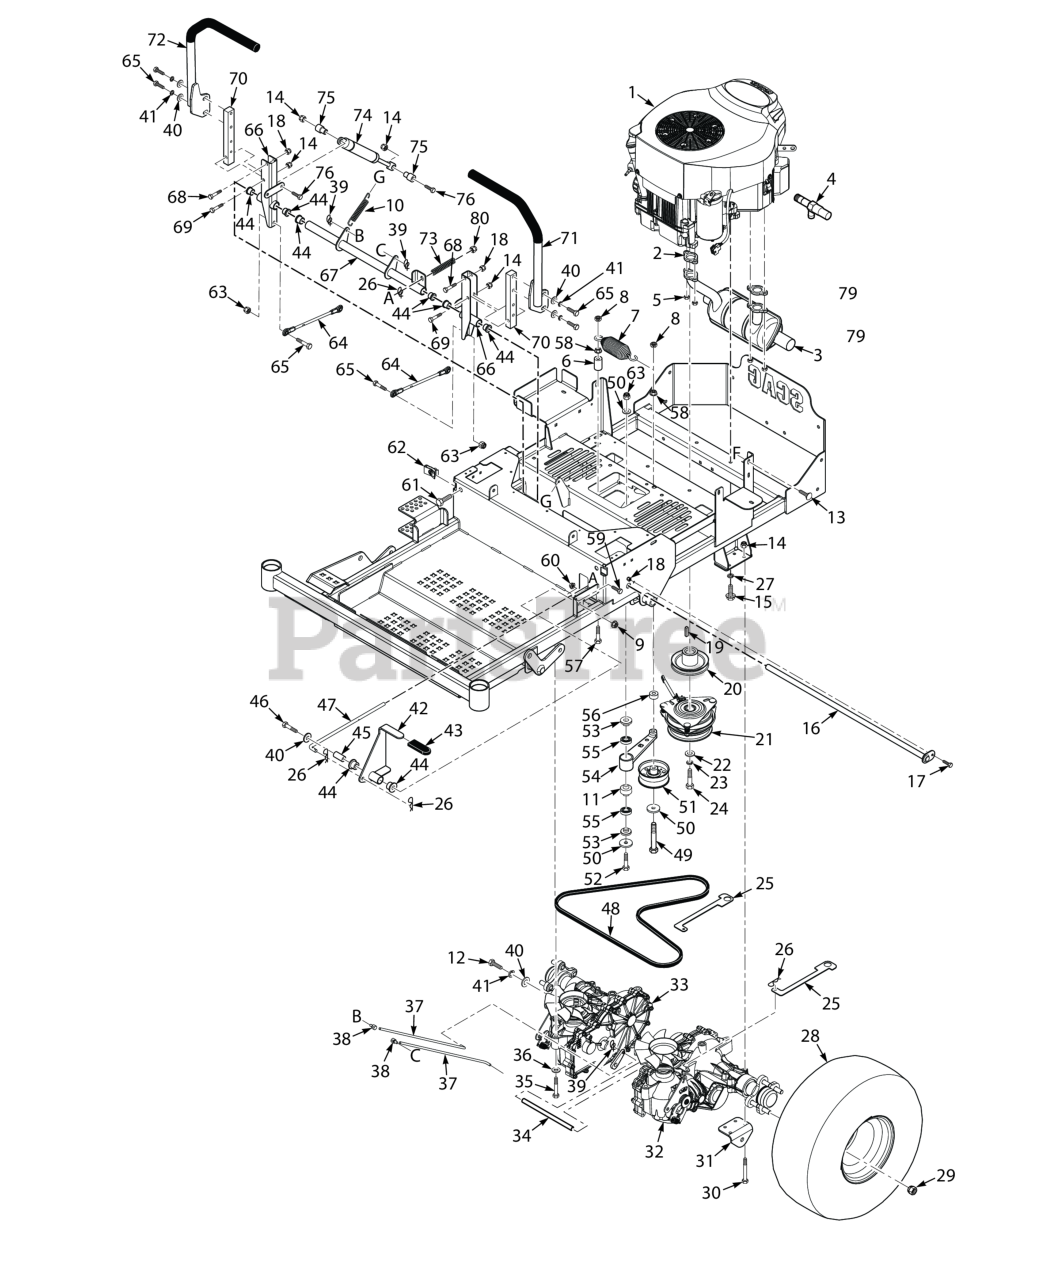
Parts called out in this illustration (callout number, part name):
1	Engine, Kawasaki 21FR
2	Gasket, Exhaust
3	Muffler, Kawasaki FR651V & FR691V
3	Muffler, Kohler KT
4	Oil Drain, Kawasaki
5	Nut, M8 x 1.25 Hex Special
6	Spacer, Idler Pulley - SFZ52
7	Spring, Transmission Drive
8	Bolt, Hex Head 3/8-16 x 1" Ser. Flg.
9	Nut, Flange Elastic Stop Nut, 3/8-16
10	Spring, Deck Latch
11	Spacer, Bearing
12	Bolt, Hex Head 3/8-16 x 2-1/4" - 61"
13	Serr. Fl. Hex Head CPSCR, 1/4-20 x 3/4"
14	HEX NUT, ELASTIC STOP LOCK, 5/16-18
15	Bolt, Hex Head 3/8-16 x 1-1/4", Kawasaki FX / FS
16	Shaft Weldment, Control Arm
17	BOLT, HEX HEAD, 1/4-20 X 5/8
18	HEX, NUT, ELASTIC STOP LOCK, 1/4-20
19	Key, 1/4 x 1/4 x 1.25" Pulley Mtg.
20	Pulley, 4-1/2" - 1" Bore
21	Electric Clutch Assembly
22	Flatwasher, 7/16-.469 x 1.75 x .25 (48, 52)
23	Lockwasher, 7/16� Spring
24	Bolt, Hex Head 7/16-20 x 3¼" w/Patch
25	Lever, Dump Valve
26	HAIR PIN, .08 DIAMETER X 1-3/16"
27	Lockwasher, 3/8" Spring, Kawasaki FX / FS
28	Wheel Assembly (48, 52)
29	Wheel Nut, 1/2-20 x 13/16
30	Bolt, Hex Head 5/16-18 x 3.00"
31	Bracket, Push Arm Link
32	Transaxle, LH - SZL
33	Transaxle, RH - SZL
34	Spacer
35	BOLT, HEX HEAD, 5/16-18 X 2-1/4
36	Flatwasher, 5/16-.375 x .875 x .083 (35BV & 37BV-EFI)
37	Rod, Brake
38	Joint, Swivel
39	Pin, Rue Cotter 3/8" Diameter
40	Flatwasher, 3/8" Special (.391 x .938 x .105)
41	Lockwasher, 3/8" Spring, Kawasaki FX / FS
42	Brake Lever Assembly
43	Grip, Brake Handle
44	Bearing
45	Pivot, Brake Lever
46	Capscrew, Hex Head 3/8-16 x 2-1/2"
47	Rod, Upper Brake Linkage
48	Belt, Transmission -SZL
49	Capscrew, Hex Head 3/8-16 x 3-3/4"
50	Flatwasher, 3/8 (.391 x .938 x .105 HD) Grade 8
51	Pulley, 3-1/2" Dia.
52	Bolt, Hex Head 3/8-16 x 3" - 52"
53	Spacer, Controls
54	Trans. Idler Arm Assy. (Includes 24, 79)
55	BEARINGS, BALL, NEUTRAL RETURN
56	Spacer, Idler Pulley - SFZ61
57	Capscrew, Hex Head 3/8-16 x 2.0"
58	NUT, 3/8-16 SERRATED FLANGE HEX HEAD
59	Capscrew, Hex Head 1/4-20 x 1"
60	NUT, 1/4-20 SERRATED FLANGE HEX HEAD
61	Bolt, Hex Head 3/8-16 x 2-1/2" Soecial Lock
62	U-Nut, 3/8-16
63	HEX NUT, ELASTIC STOP LOCK, 3/8-16
64	Linkage, Pump
65	Bolt, Hex Head 3/8-16 x 1-1/4", Kawasaki FX / FS
66	Control Arm Assembly
67	Bellcrank Assembly (incl. 44)
68	Bolt, Hex Head, 1/4-20 x 1-1/4"
69	Bolt, Hex Head 5/16-18 x 1-1/2" - Front
70	Bar, Control Lever
71	Handlebar w/Grip
72	Handlebar w/Grip
73	Spring, Brake
74	Damper, Steering
75	Spacer, Pump Dampener
76	Bolt, Hex Head 5/16-18 x 1-1/2" (Right Front Engine Mounting, Briggs and Kohler Only)
